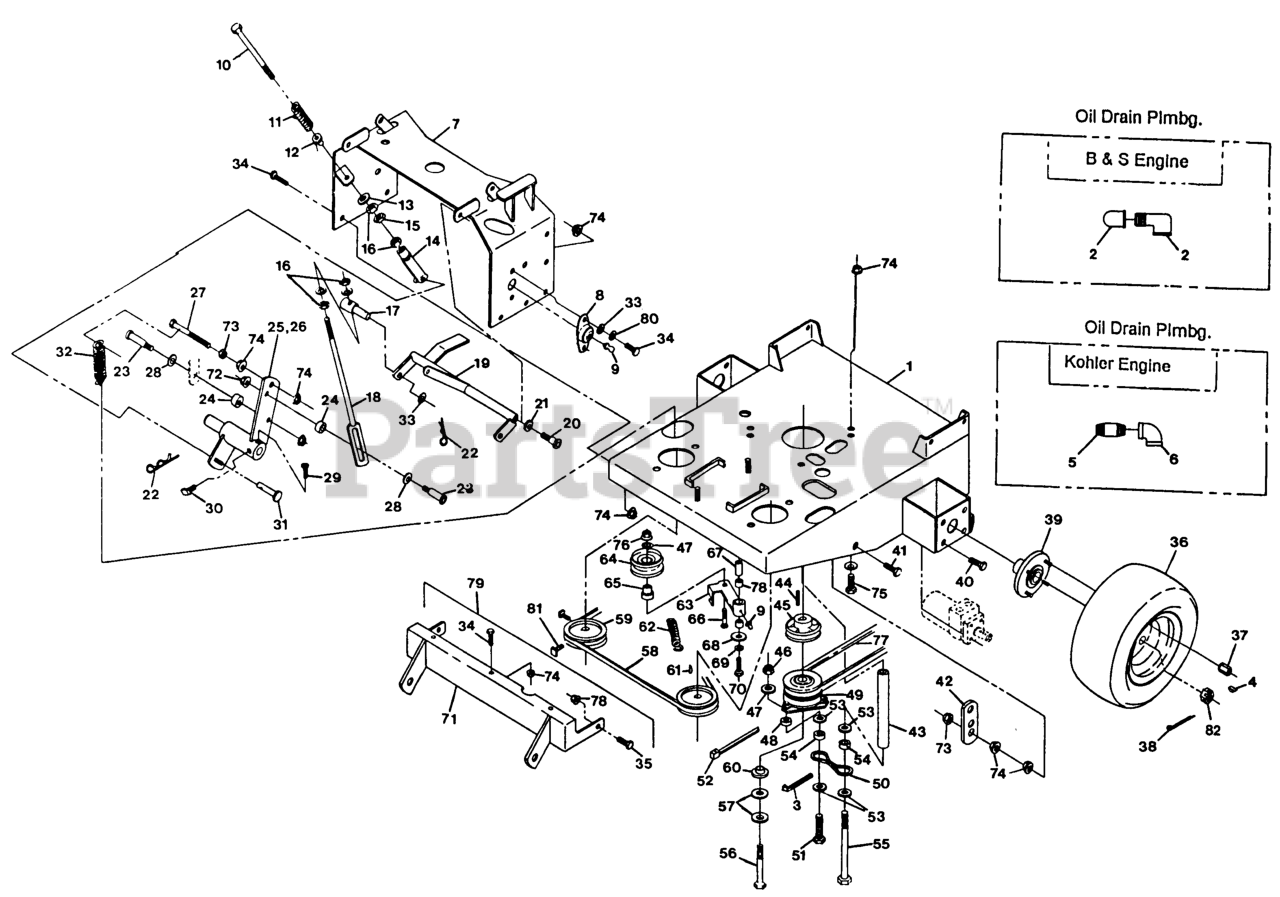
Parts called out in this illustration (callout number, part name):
1	Engine Deck Weldment
2	FITTING-ELBOW-90
3	TIE-CABLE
4	KEY-WOODRUFF
5	NIPPLE,PIPE
6	ELBOW-90 DEG
8	FLANGE MTG, SIDE
10	BOLT-RETURN, NEUTRAL
11	SPRING-RETURN, NEUTRAL
12	BUSHING-FLANGED
14	YOKE-ADJUSTABLE
20	SCREW-HSH
22	PIN-COTTER
23	SCREW-HSH
26	WLD,LH CONTROL ARM
30	SCREW-SET
31	PIN-CLEVIS
32	SPRING-EXTENSION
38	PIN-COTTER
41	BOLT-TAP, HH
42	ANCHOR-SPRING
52	TIE-PLASTIC
54	SPACER,CLUTCH ANCHOR
57	WASHER-SPRING
58	BELT-HYDRO TRANS DR
59	SHEAVE - PUMP
60	BUSHING,CLUTCH KEEPER
62	SPRING-EXTENSION
63	IDLER ARM ASM
65	BUSHING-IDLER
67	BUSHING
71	WLD,SULKY HITCH
77	Belt/Shield Kit (60")
78	SLEEVE-BEARING
79	Turf Tracer Hydro Kit, Hitch Sulky
80	WASHER-LOCK
81	SCREW-SET
